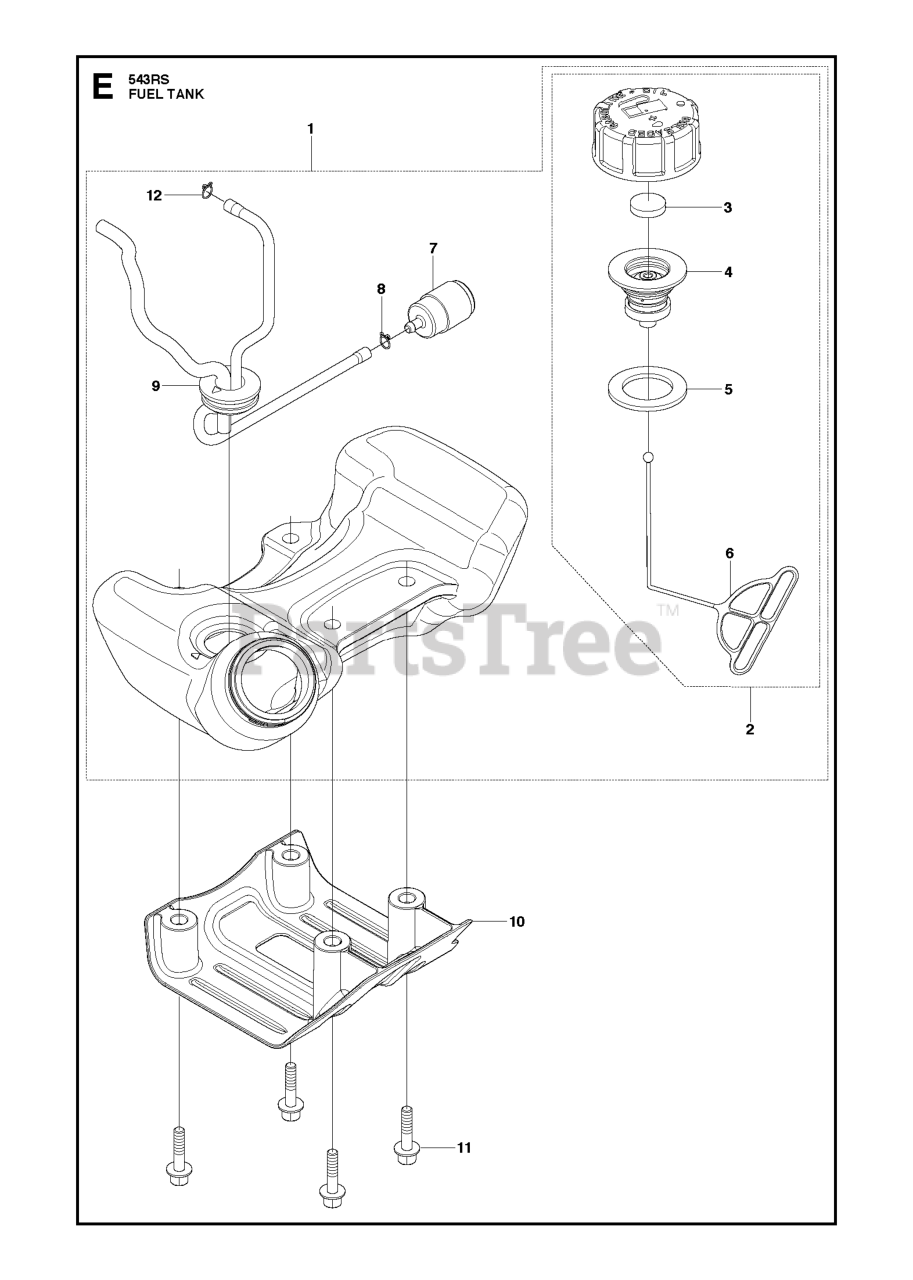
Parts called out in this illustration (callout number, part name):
1	TANK ASSY
2	ASSY FUEL CAP
7	FILTER ASSY
9	PIPE COMP
10	GUARD, TANK
11	BOLT M5X25
12	CLAMP FUEL LINE
